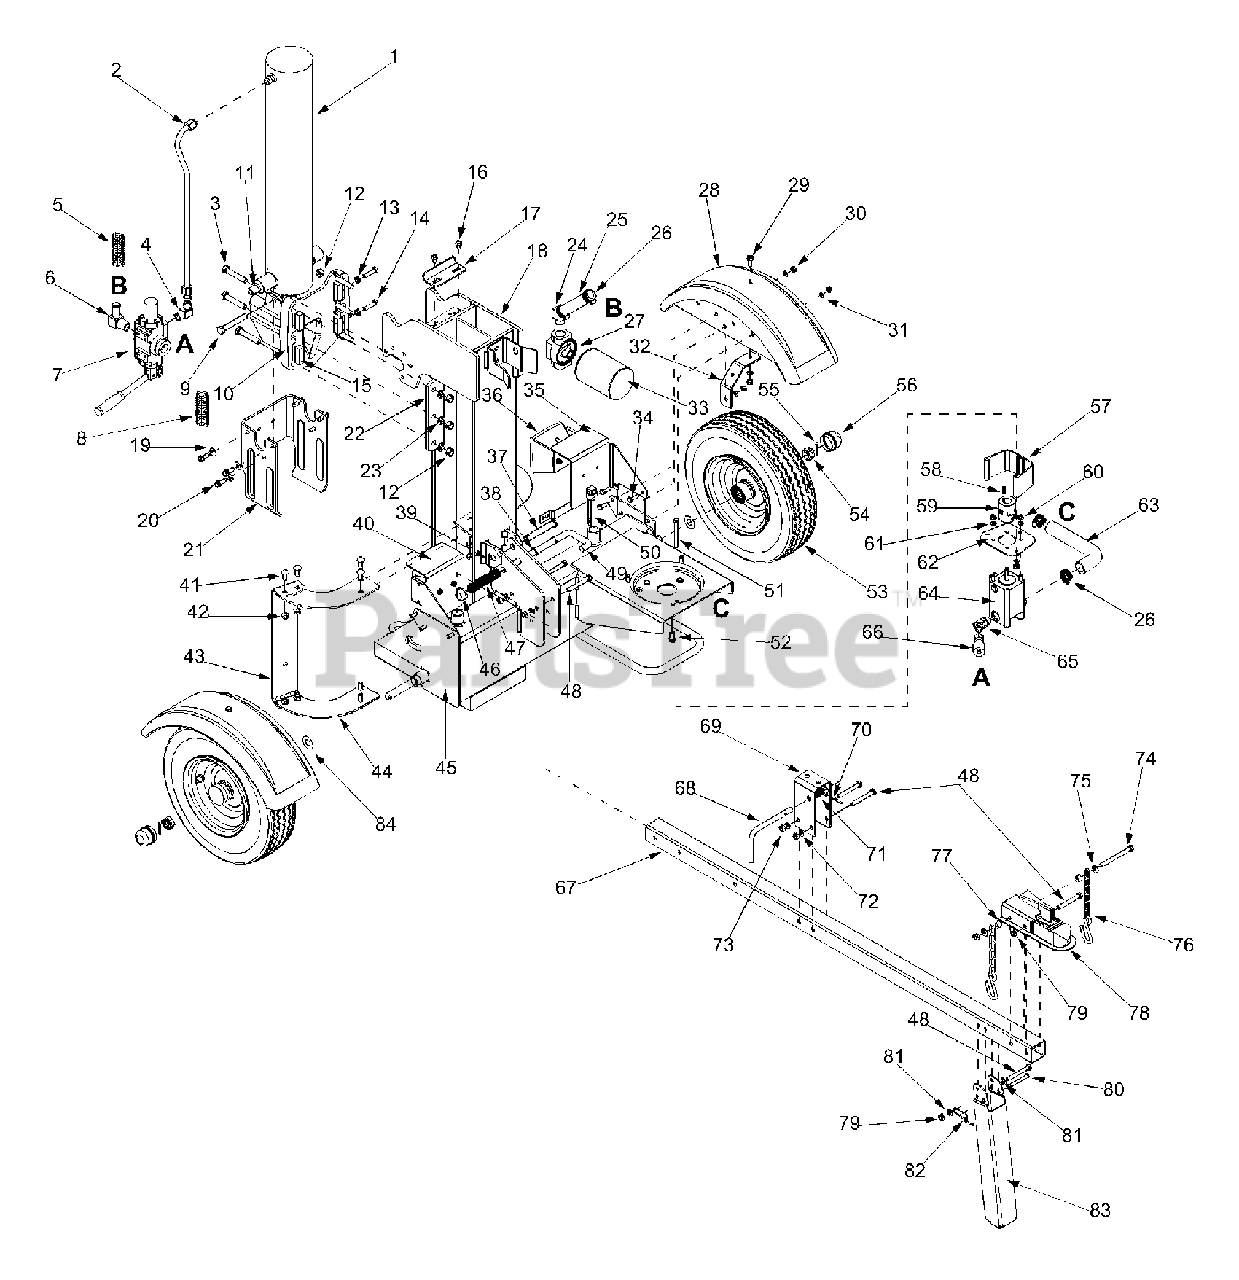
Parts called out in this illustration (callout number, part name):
1	Hydraulic Cylinder
1	Seal Kit 4.5" for Fisher Cylinder 718-0769
1	Kit Seal 4.5" for XINGHUI cylinder 718-0769A
1	Kit Seal 4.5" for ENERGY cylinder 718-0769A
2	Hydraulic Tube
3	Hex Cap Screw 1/2-20 x 2.75
4	90 Degree Solid Adapter
5	Hose Guard
6	Return Elbow
8	Hose Guard
9	Hex Cap Screw 1/2-20 x 3.50
10	Wedge Assembly
11	Nipple Pipe 1/2-14
12	Lock Nut 1/2-20
13	Hex Jam Nut 3/8-24
14	Hex Cap Screw 3/8-24 x 1.5
16	Hex Washer Screw 5/16-18 x .625
19	Flat Washer .406 ID x .875 OD
20	Hex Washer Screw 3/8-16 x 1.0
23	Lock Washer 1/2
24	Adapter 3/4-14
25	Return Hose 3/4" ID x 44" Lg.
26	Hose Clamp 5/8"
27	Filter Housing
28	Fender, Plastic
28	Fender, Plastic Red
29	Hex Washer Screw 5/16-18 x .875
30	Hex Nut 5/16-18
31	Lock Washer 5/16
33	Oil Filter
34	Hex Cap Screw 5/16-18 x 1.0
36	Taillight
36	RH Taillight Assembly
36	LH Taillight Assembly
36	Wiring Harness
37	Clevis Pin
38	Flat Washer .635 ID x .93 OD
39	Cotter Pin
41	Carriage Bolt 3/8-16 x 1.0
42	Flanged Lock Nut 3/8-16
46	Push Cap
47	Compression Spring
48	Hex Bolt 3/8-16 x 3"
49	Lock Rod
50	Vented Dipstick
51	Hex Screw 5/16-24 x 3.25
52	Hex Washer Screw 3/8-16 x 1.0
53	Wheel Assembly
54	Slotted Nut 3/4-16
55	Cotter Pin
56	Hub Cap
57	Coupling Shield
58	Square Key 3/16" x .75
59	Flexible Coupling .750 x .500
59	Flexible Coupling .875 x .500
59	Flexible Coupling .875 x .437
60	Hex Nut 5/16-24
61	Lock Washer 5/16" ID
64	Gear Pump (11 gpm)
64	Pump Kit
64	Gear Pump (9.5 gpm)
65	45 Degree Elbow
66	High Pressure Hydraulic Hose
68	Latch Rod
70	Spiral Pin
71	Spring Compression
72	L-Washer 3/8"
73	Hex Nut 3/8-16
74	Hex Cap Screw 3/8-16 x 4.25
75	Flat Washer .385 ID x .870 OD
76	Chain
77	Spacer .375 ID x .625 OD
78	Coupling Hitch
79	Hex Lock Nut 3/8-16
80	Clevis Pin
81	Flat Washer .375 ID x .738 OD
82	Spring Pin
